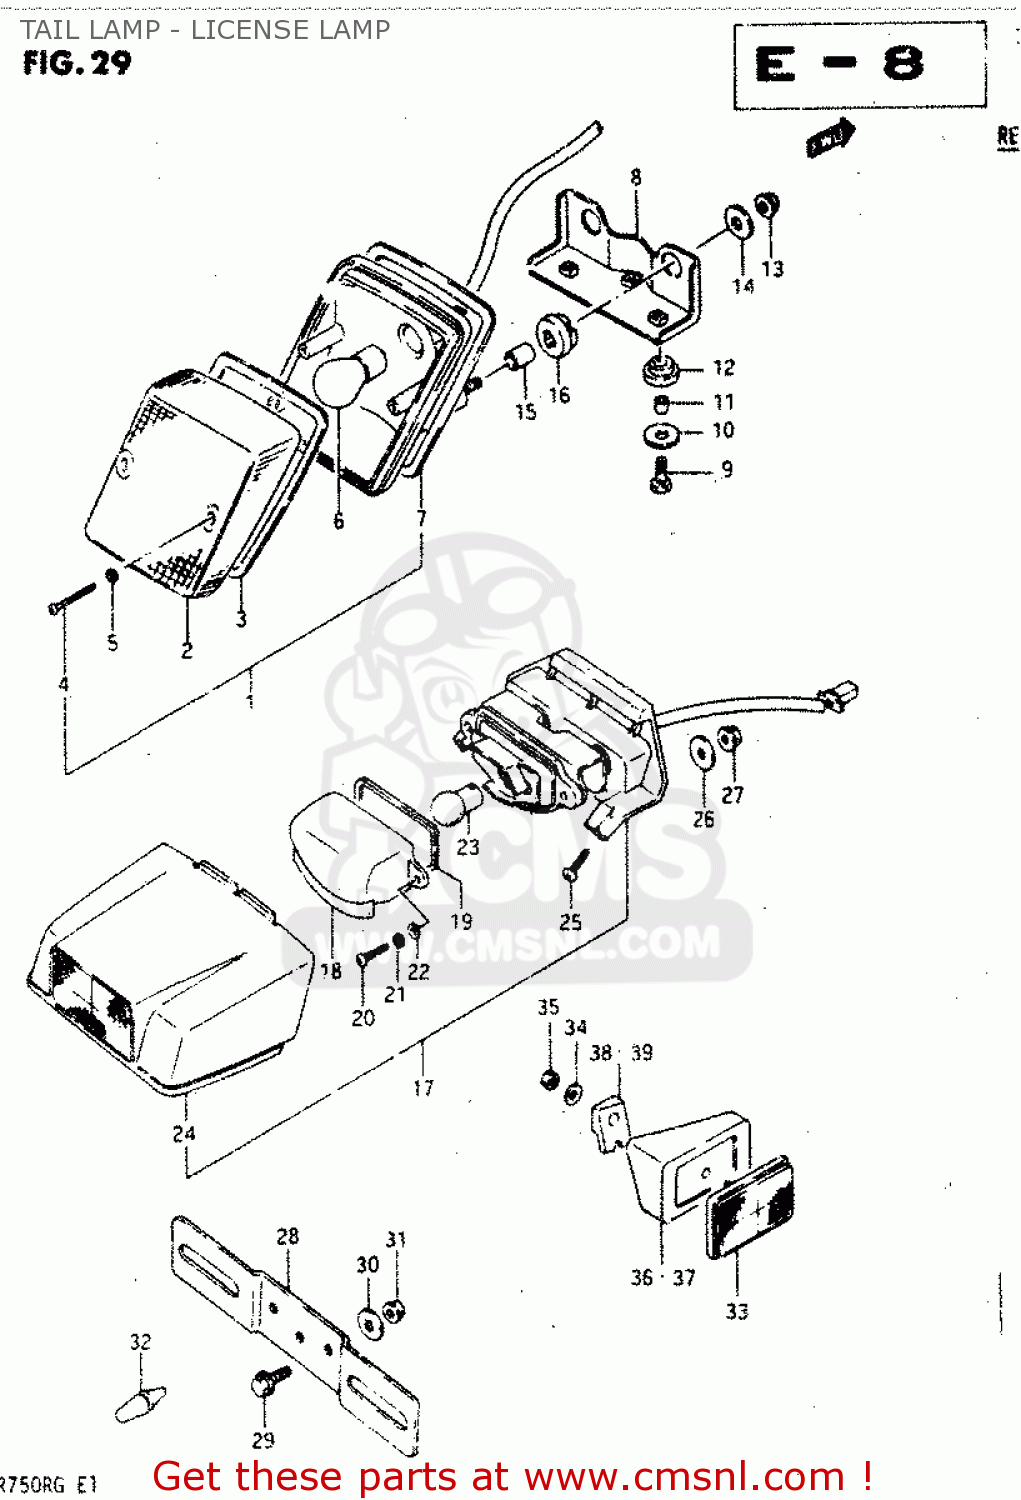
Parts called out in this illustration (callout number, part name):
1	LAMP ASSY, REAR COMBINATION
2	LENS,RR COMBI
3	GASKET,REAR COMBINATION LAMP
4	SCREW TAPP.
5	GASKET (NAS)
6	BULB(12V21/5W)
7	GASKET
8	BRACKET,REAR COMBINATION LAMP
9	BOLT,M6X1X20
10	WASHER
11	SPACER (6.1X9X7.5)
12	CUSHION
13	NUT
14	WASHER
15	SPACER (6.4X9X10.5)
16	CUSHION
17	LAMP ASSY,LICENSE
18	LENS,LICENSE LAMP
19	GASKET,LICESE LAMP (NAS)
20	SCREW
21	WASHER,LOCK 4M
22	WASHER 4MM
23	BULB
24	COVER,LICENSE LAMP
25	SCREW
26	WASHER (5.5X20X1.2)
27	28
28	PLATE,RR LICENSE
29	BOLT
30	WASHER
31	NUT
32	CUSHION
33	REFLEX REFLECTOR, REAR SIDE
34	WASHER(5.2X16X1)
35	NUT ,5MM
36	SPACER
37	SPACER
38	WASHER
39	SPACER, INNER LH
